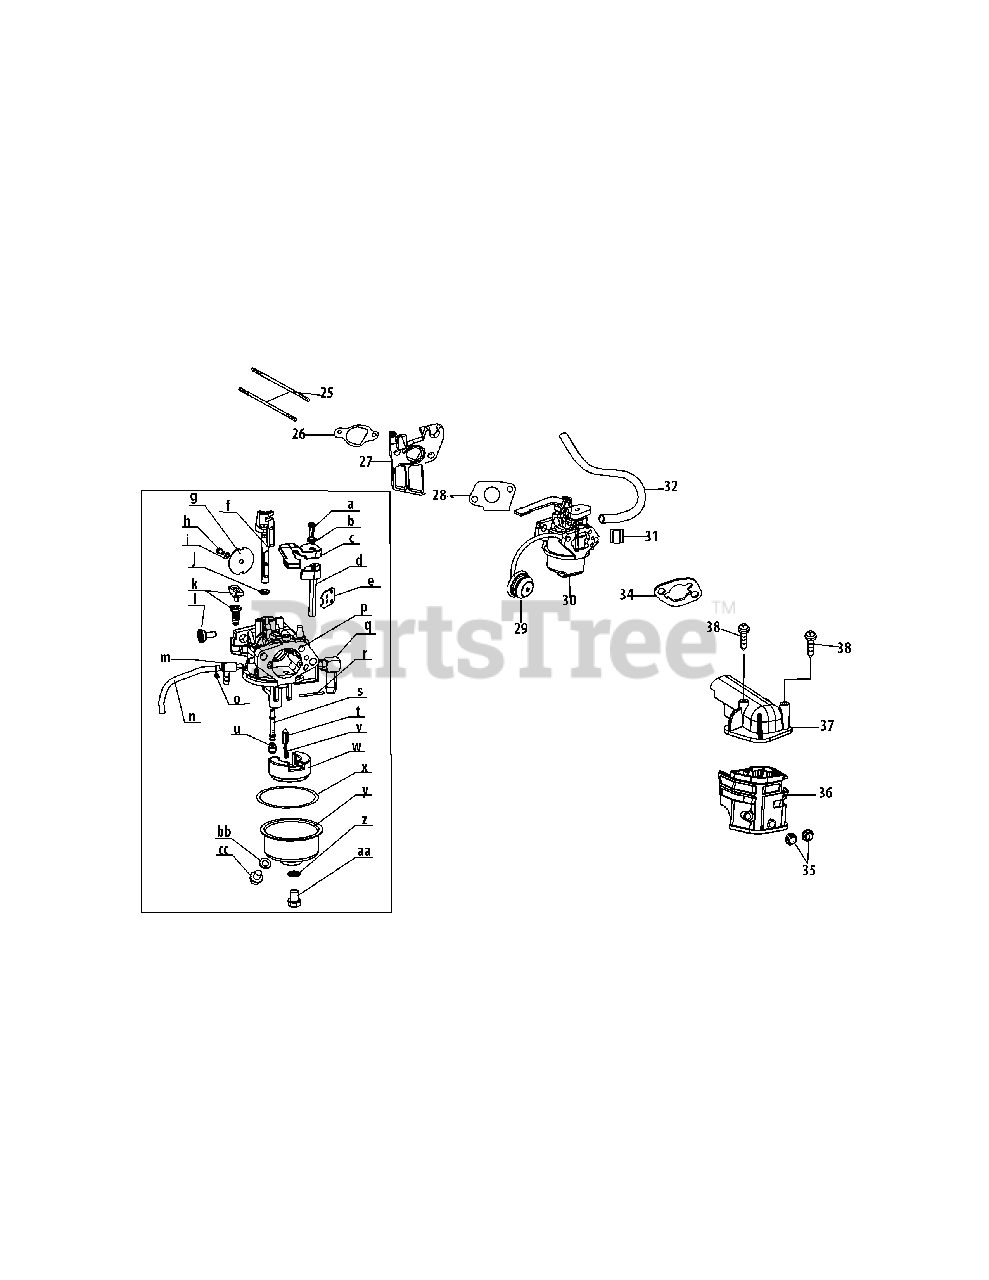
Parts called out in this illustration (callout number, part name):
25	Stud, M6×113, Intake
26	Carburetor Insulator Gskt
27	Carburetor Insulator
28	Packing
30	Carburetor Assy
31	Fuel Hose Clamp
34	Gasket, Intake
35	Nut, Flange, M6
36	Base, Heater Box
38	Self-Tapping Screw
